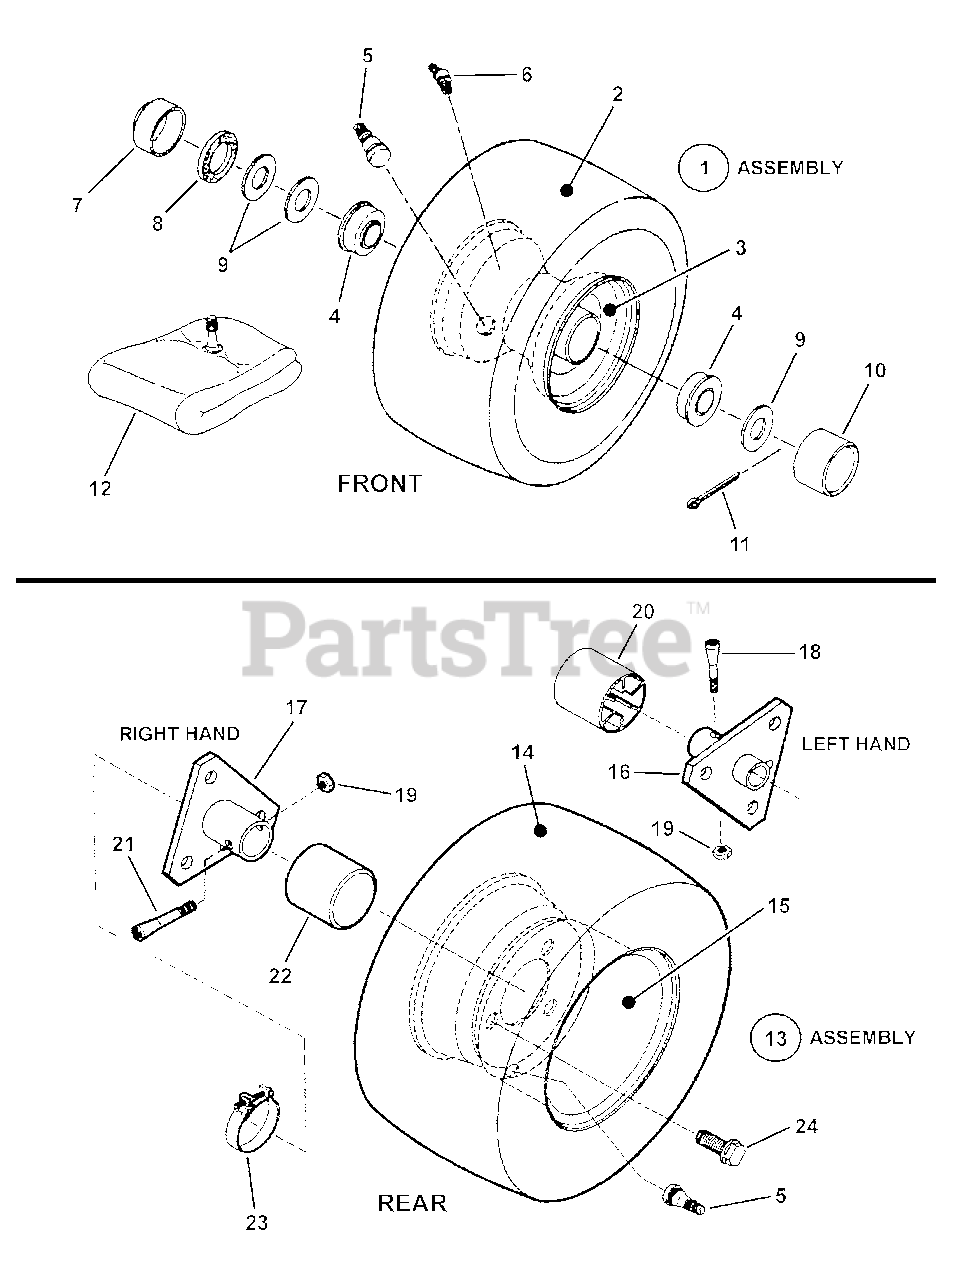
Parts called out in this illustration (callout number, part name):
1	ASSEMBLY, Front Tire & Rim (Complete)
2	TIRE, 11 x 4.00-4 (Kenda)
3	RIM (For 4.10/3.50 x 4 Tire)
4	BALL BEARING, Flange (3/4" I.D.)
5	VALVE STEM, Snap In
6	* LUBE Fitting, Straight (for 3/16" hole)
6	* LUBE Fitting, Straight (for 1/4" hole)
6	* LUBE Fitting, 90 Degree, Ball Check (for 1/4" hole)
6	* LUBE Fitting, 90 Degree, Ball Check (for 5/16" hole)
7	CAP, Dust
8	FELT SEAL
9	WASHER, .77 x 1.13 x .06 Flat
10	HUB CAP
11	COTTER PIN, 5/32 x 1"
12	TUBE, Inner (For 4.10/3.50 x 4 Tire)
13	ASSEMBLY, Rear Tire & Rim (28", 30", 33" Models)
14	TIRE, 16-6.50 x 8
15	RIM, Extra Wide (For 16/7.50 x 8 Tire) (33" Models)
16	HUB, Rear Wheel L. H. (Weldment)
17	HUB, Rear Wheel R. H. (Weldment)
18	AXLE BOLT, Left Hand (5/16-24 x 1-5/8" Tapered)
19	NUT, Wheel Bolt, 5/16-24 Hex Center Lock
20	CAP, Hub, L. H. (Long Axle)
21	WHEEL BOLT, Right Hand (5/16-24 x 2" Tapered)
22	CAP, Hub
23	CLAMP, Right Hand 2"
24	BOLT, 1/2-20 x 3/4" Lug, GR 5
